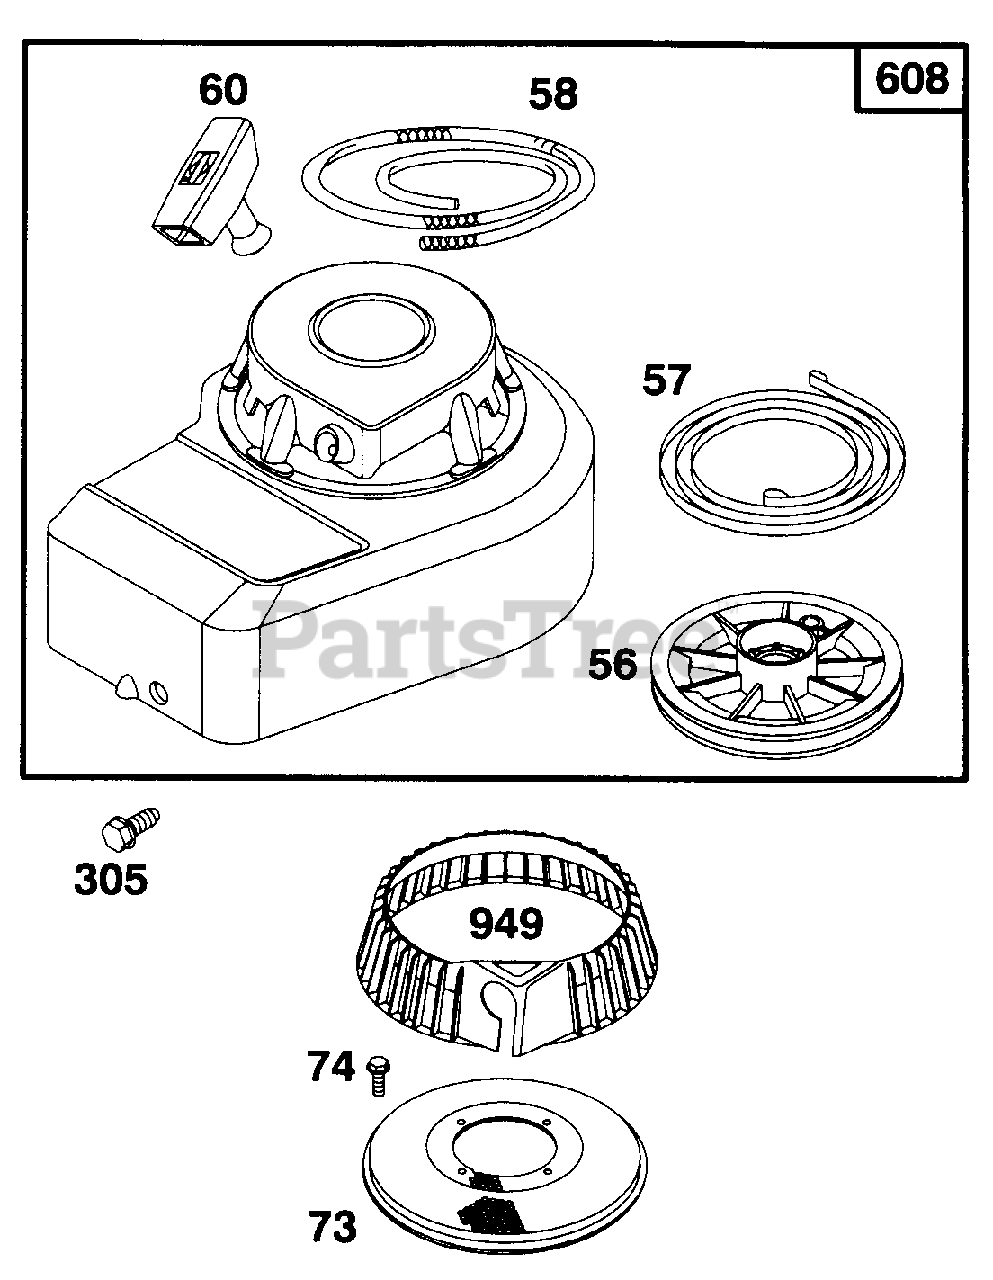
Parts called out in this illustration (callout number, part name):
56	Pulley--Rewind Starter
57	Spring--Rewind Starter
58	Rope--Rewind Starter (81" Long)
60	Grip--Starter Rope
73	Screen--Rewind Starter
74	Screw--Sem
305	Screw--Hex Head
608	Starter Ass'y.--Rewind (5 o'clock)
949	Guard--Rewind Starter
